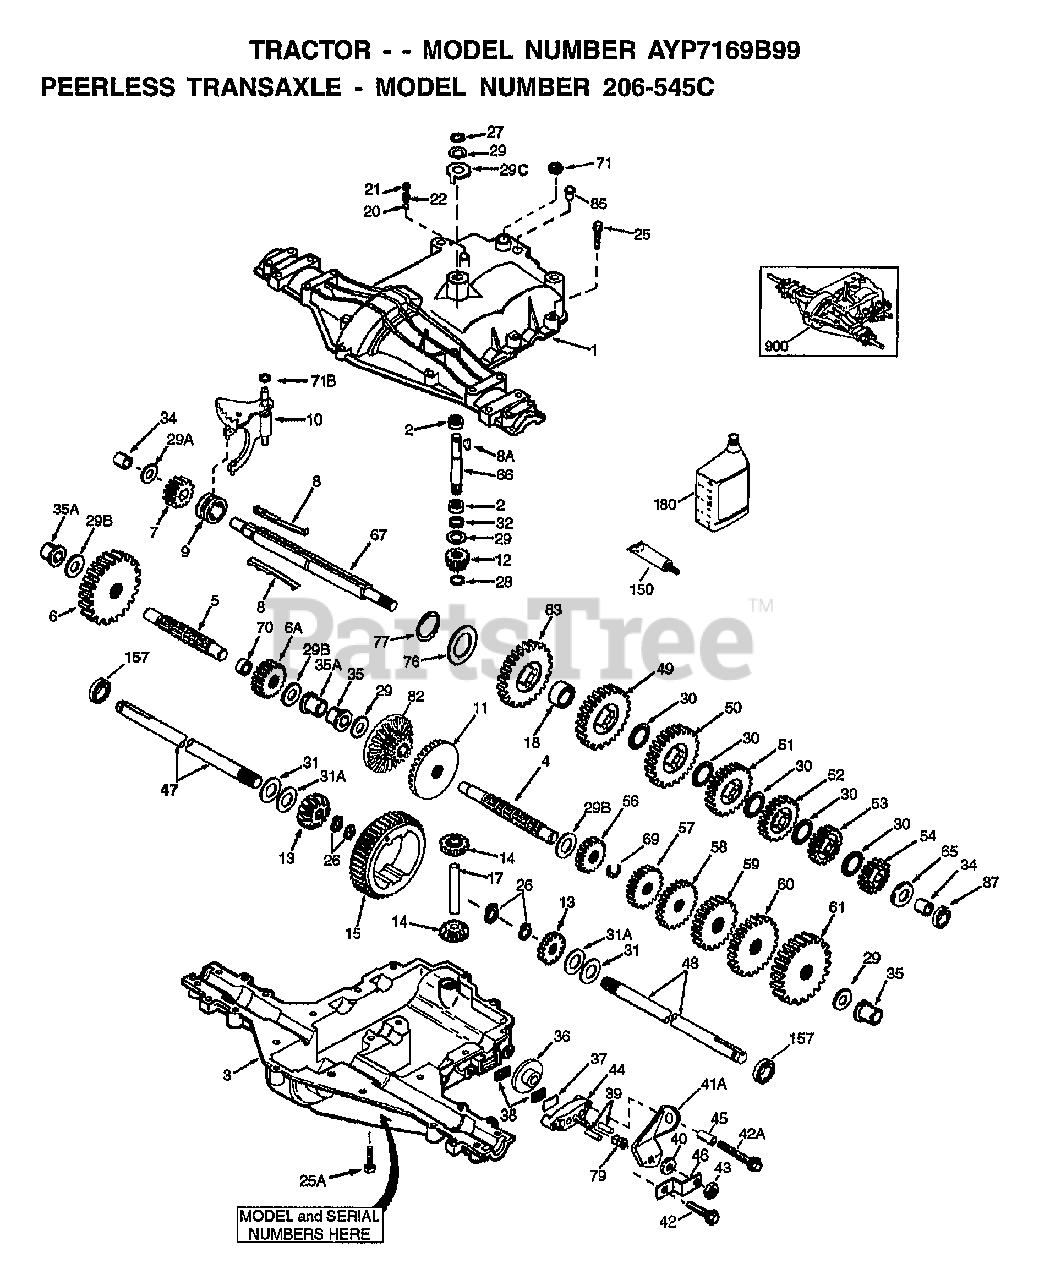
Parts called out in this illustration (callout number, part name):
1	TRANSAXLE COVER
2	NEEDLE BEARING 5/8" ID
3	TRANSAXLE CASE
4	COUNTERSHAFT
5	OUTPUT SHAFT
6	SPUR GEAR (38 TEETH)
6A	SPUR GEAR (15 TEETH)
7	SPUR GEAR (11 TEETH)
8A	KEY, WOODRUFF
9	COLLAR, SHIFTER
10	SHIFT ROD & FORK
11	BEVEL GEAR (30 TEETH)
12	INPUT BEVEL PINION (13TEETH)
13	BEVEL GEAR (13 TEETH)
14	BEVEL GEAR (13 TEETH)
15	RING GEAR (43 TEETH)
18	SPACER, NEUTRAL
21	SCREW, 3/8-16 X 3/8"
25A	SCREW 1/4-20 X 1-3/8"
26	RING RETAINER
27	RING, RETAINER
28	RETAINING RING
29	WASHER THRUST
29B	WASHER THRUST
29C	P/N CONFLICT - CHECK WITH SUPPLIER
30	WASHER THRUST
31A	FLAT WASHER
32	OIL SEAL 5/8"
34	BUSHING 9/16"
35	FLANGED BUSHING 5/8" ID
35A	FLANGED BUSHING 3/4"
37	PLATE BRAKE PAD
41A	BRAKE LEVER
42A	SCREW, 1/4-20 X 2-1/4
43	LOCKNUT 5/16-24
44	HOLDER BRAKE PAD
46	BRKT BRAKE LEVER
49	SPUR GEAR (29 TEETH)
50	SPUR GEAR (27 TEETH)
51	SPUR GEAR (23 TEETH)
52	SPUR GEAR (19 TEETH)
53	SPUR GEAR (16 TEETH)
54	SPUR GEAR (15 TEETH)
56	SPUR GEAR (11 TEETH)
57	SPUR GEAR (13 TEETH)
58	SPUR GEAR (17 TEETH)
59	SPUR GEAR (21 TEETH)
60	SPUR GEAR (24 TEETH)
61	SPUR GEAR (25 TEETH)
66	INPUT SHAFT
67	SHIFTER & BRAKE SHAFT
69	RETAINING RING
70	SPACER .890
71	SEAL SQUARE CUT
76	WASHER, THRUST
77	INVERTED RETAINING RING
82	BEVEL & SPUR GEAR (30 & 13 TEETH)
83	SPUR GEAR (27 TEETH)
85	OIL FILL PLUG
150	LIQUID GASKET RTV SILICONE
180	GEAR OIL 80W90
900	REPLACEMENT TRANSAXLE
